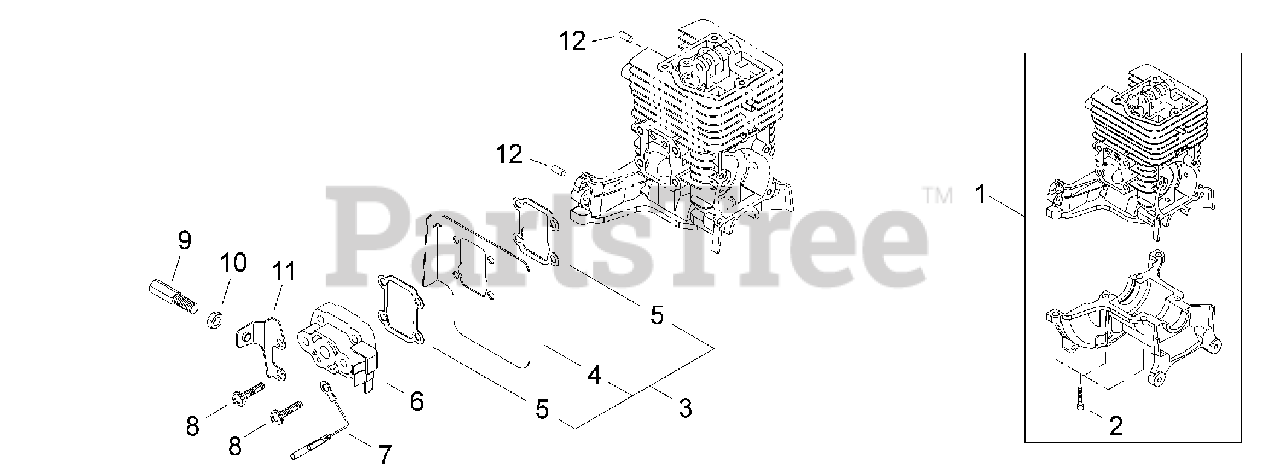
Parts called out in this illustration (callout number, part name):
1	CYLINDER BLOCK SET
2	SCREW - 5X16
3	HEAT DEFLECTOR ASSY
4	DEFLECTOR, HEAT
5	SHIELD, INTAKE
6	INSULATOR
7	LEAD - GROUND
8	SCREW - 5X22
9	NUT, CABLE ADJUST
10	LOCKNUT - 6
11	BRACKET, THROTTLE CABLE
12	PIN - LOCATING
